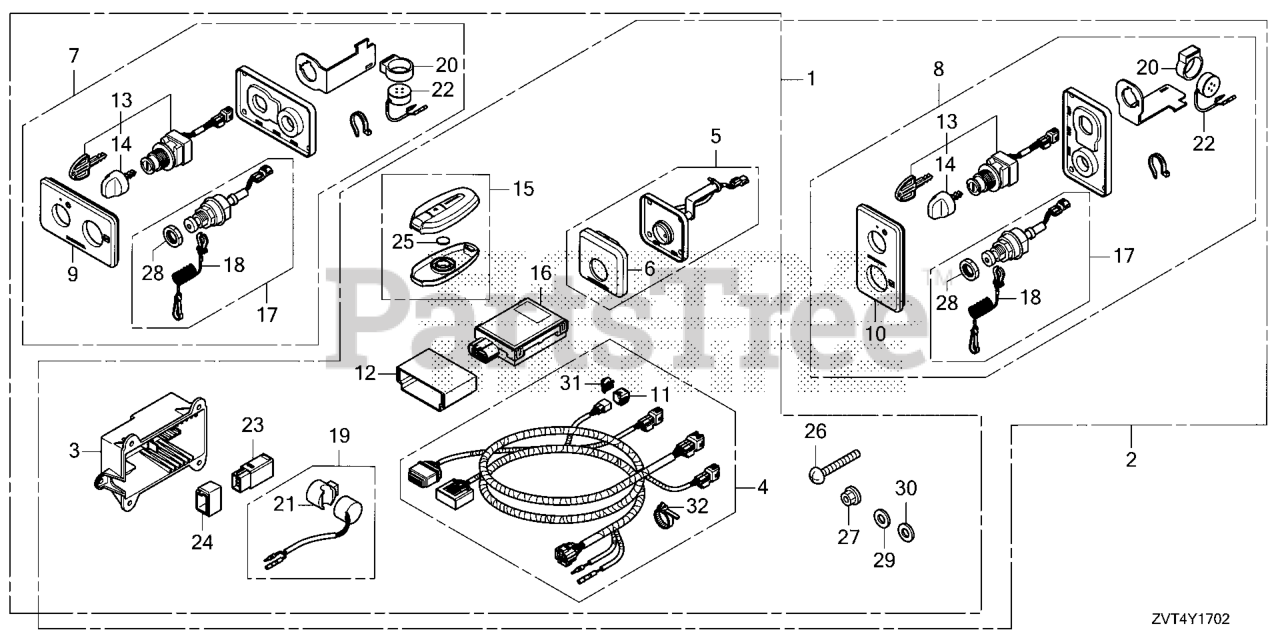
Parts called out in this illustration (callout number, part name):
1	UNIT KIT, SMART KEY
2	UNIT KIT, SMART KEY
3	CASE, CONTROL UNIT (SMART)
4	HARNESS ASSY., SMART KEY CONTROL
5	PANEL ASSY., START STOP (SINGLE)
6	PANEL, START STOP (SINGLE)
7	PANEL ASSY., KEY SWITCH (SMART)
8	PANEL ASSY., KEY SWITCH (SMART)
9	PANEL, KEY SWITCH
10	PANEL, KEY SWITCH
11	CAP, DUMMY (WPC 4P 090 M) (RED)
12	SUSPENSION, CONTROL UNIT (SMART)
13	SWITCH ASSY., COMBINATION (SMART)
14	KNOB
15	FOB ASSY. (315MHZ) (NOT AVAILABLE)
16	CONTROL UNIT, SMART (315MHZ)
17	SWITCH ASSY., EMERGENCY STOP
18	WIRE, EMERGENCY
19	BUZZER ASSY., WARNING
20	SUSPENSION, AUDIBLE PILOT
21	SUSPENSION, WARNING BUZZER
22	BUZZER, WARNING
23	RELAY ASSY., MAIN
24	SUSPENSION, RELAY
25	BATTERY (CR2025) (MSDS)
26	SCREW, PAN (5X40) DUAL QTY = (8) (SINGLE)
27	NUT, FLANGE (5MM)
28	NUT
29	WASHER, PLAIN (5MM)
30	WASHER, SPG (5MM)
31	CLIP, CONNECTOR (DARK BROWN)
32	CLIP, HARNESS BAND (145MM) (BLACK)
